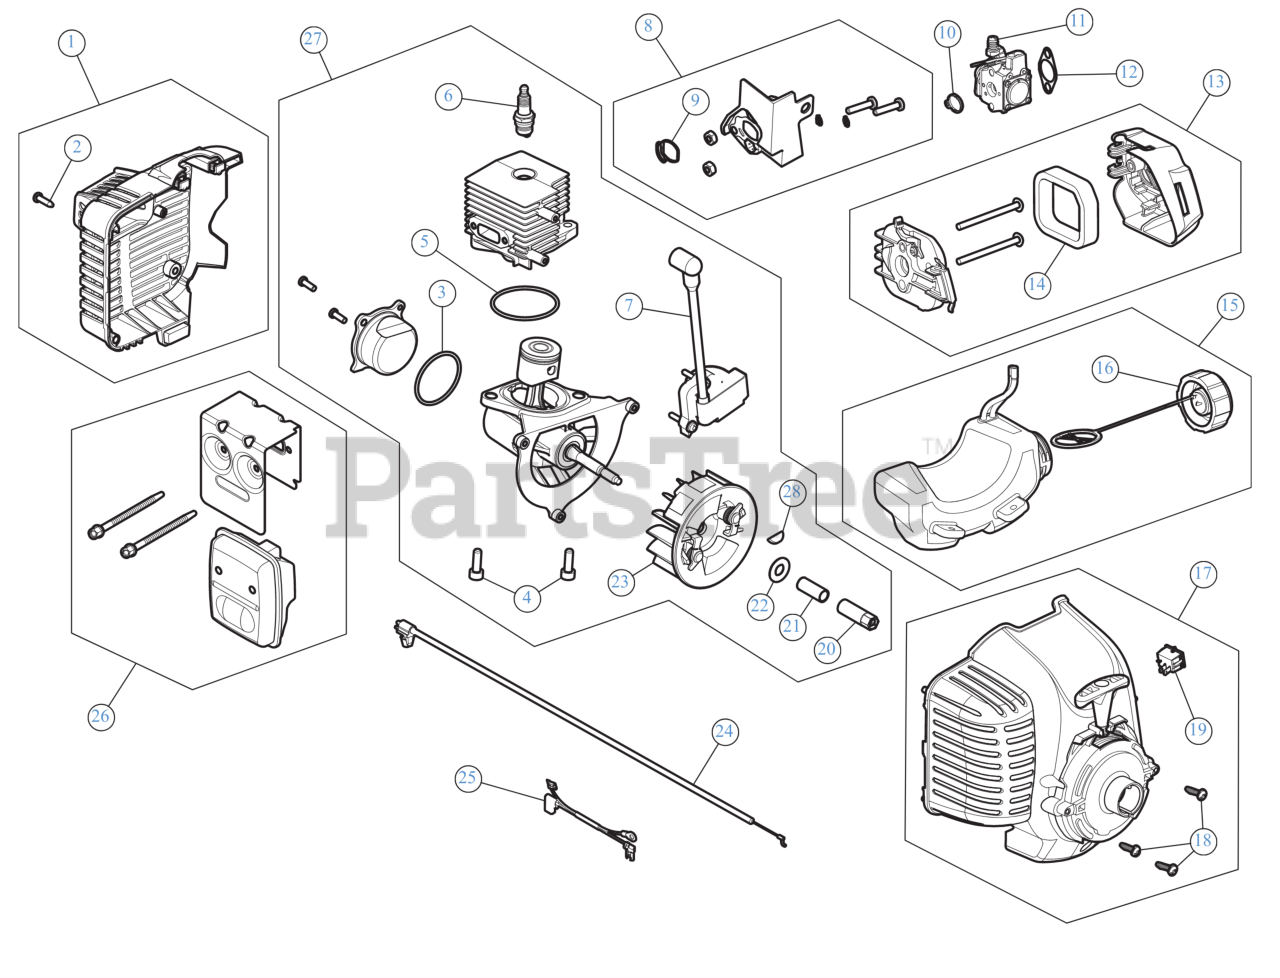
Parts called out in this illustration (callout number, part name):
1	HOUSING ASSEMBLY RR
2	SCREW 8-16 x 3/4
3	O-RING SEAL CRANKCASE
4	SCREW 5/16-18x3/4 T40
5	O-RING SEAL CYLINDER
6	SPARK PLUG
7	MODULE ASSEMBLY
8	INTAKE ASSEMBLY
9	INSL/CYL SEAL
10	CARBURETOR SEAL
11	CARBURETOR
12	GASKET CARB
13	AIR CLEANER
14	AIR FLITER
15	FUEL TANK ASSEMBLY
16	FUEL CAP ASSEMBLY
17	STARTER HOUSING
18	SCREW #
19	SW, MOMENTARY ON/O
20	POWER SHAFT ADAPTER
21	SPACER CRANKSHAFT
22	BELL WASHER
23	FLYWHEEL ASSEMBLY
24	THROTTLE CABLE
25	SHORT WIRE LEAD
26	MUFFLER ASSEMBLY
27	SHORT BLOCK
28	WOODRUFF KEY #403-.125 x .375
